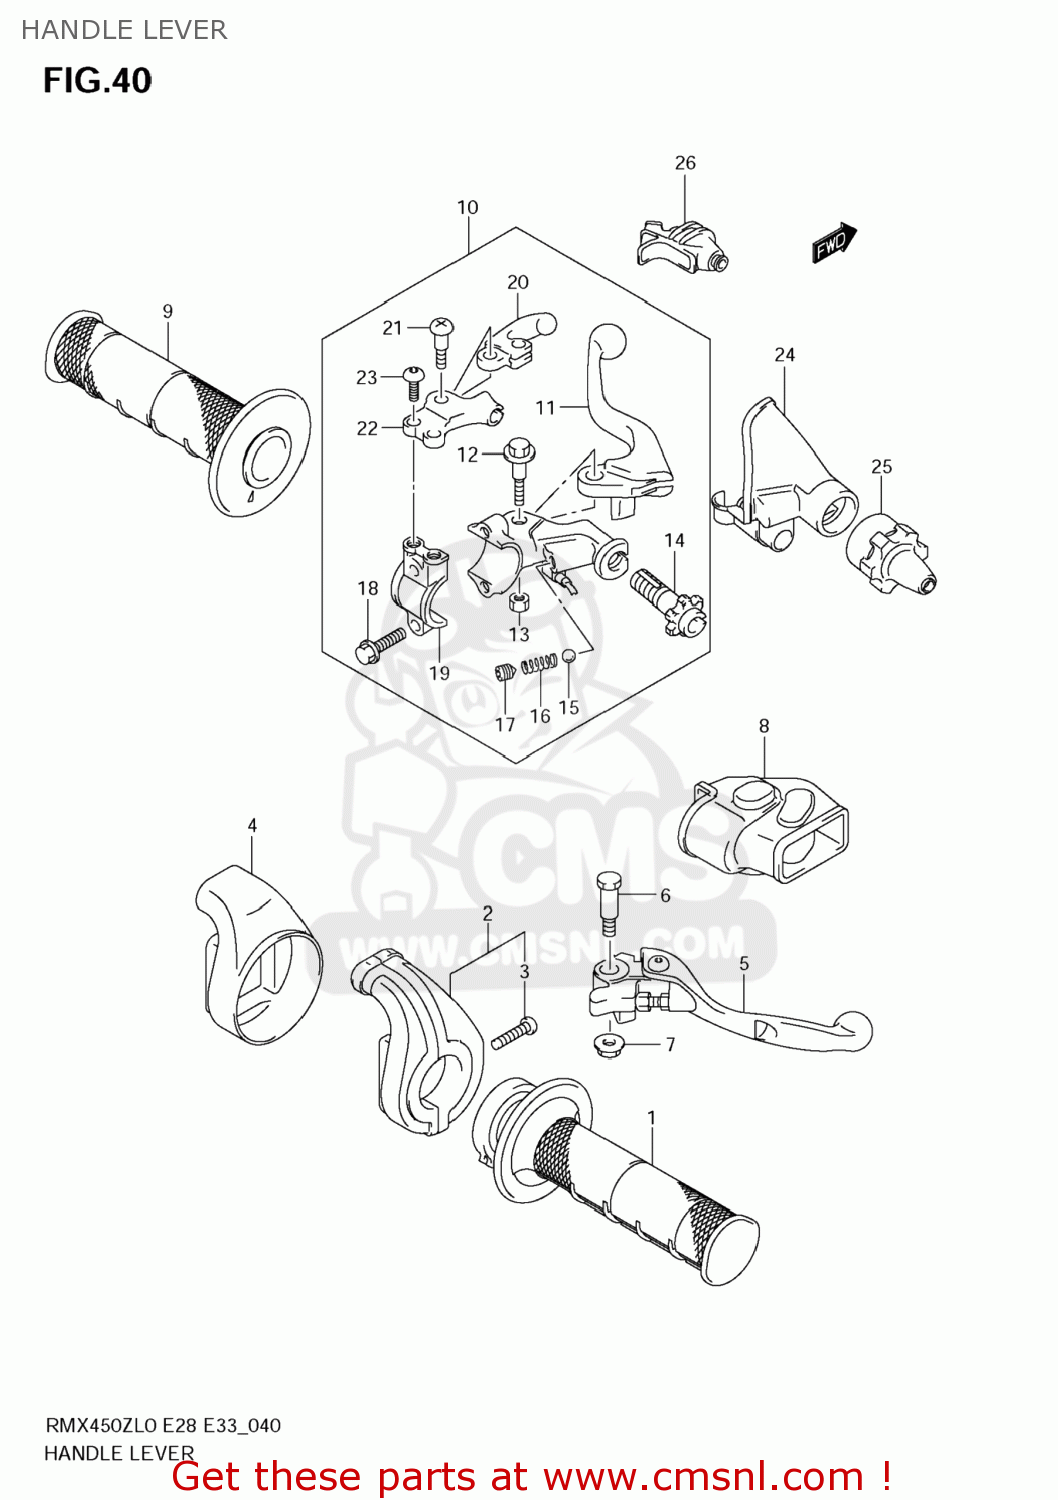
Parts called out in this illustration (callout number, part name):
1	GRIP,THROTTLE
2	CASE ASSY,THROTTLE
3	SCREW,CASE
4	COVER,THROTTLE CASE
5	LEVER ASSY,BRAKE
6	BOLT,BRAKE LEVER
7	NUT
8	COVER,BRAKE LEVER
9	GRIP,L
10	LEVER ASSY,CLUTCH
11	LEVER,CLUTCH
12	BOLT
13	NUT
14	ADJUSTER,CABLE
15	BALL
16	SPRING
17	SCREW(6X8)
18	BOLT,BRACKET
19	HOLDER,CLUTCH LEVER
20	LEVER,HOT STARTER
21	BOLT,HOT STARTER LEVER
22	HOLDER,HOT STARTER LEVER
23	SCREW(5X12)
24	COVER,CLUTCH LEVER
25	COVER,CLUTCH ADJUSTER
26	COVER,HOT STARTER LEVER
